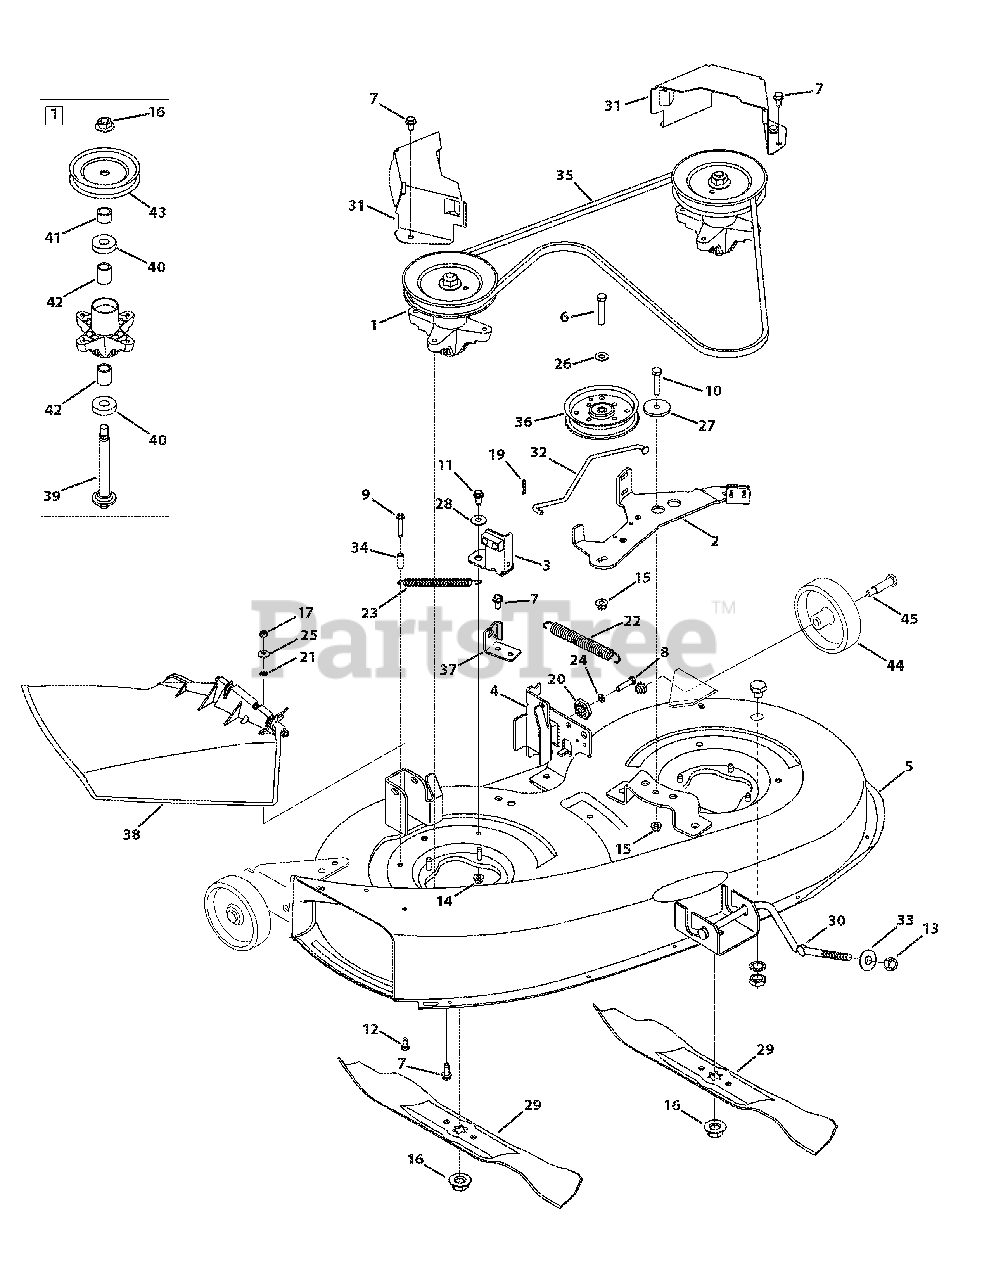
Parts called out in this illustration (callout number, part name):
1	Pulley Spindle Ass’y 5.75 dia.
2	Deck Brake Assembly
3	Deck Brake Assembly
4	Deck Hanger Brkt. Ass'y
5	Deck Shell, 38" (w/ wheel brackets)
6	Hex Screw 3/8-16 x 1.75
7	S-Tapp Scr 5/16-18 x .75
8	Hex Wash Tap Scr 5/16-18 x 1.25
9	Hex Wash HD Bolt 1/4-20 x 1.50" Lg.
10	Hex Bolt 3/8-16 x 1.25
11	Hex Bolt 5/16-18 x .75" Lg. Gr. 5
12	Hex Bolt 1/4-20 x 1.00
13	Flexloc Nut 1/2-13
14	Hex Flange Locknut 5/16-18 Gr. F, Nylon
15	Hex Flange Locknut 3/8-16 Gr. F Nylon
16	Hex Flange Locknut 5/8-18
17	Hex Nut 1/4-20 Gr. 5
19	Int. Cotter Pin .072 x 1.13" Lg.
20	Deck Adjustment Gear
21	Bolt Retainer 1/4" x .50" OD
22	Extension Spring .75 dia. x 6.37 Lg.
23	Extension Spring .50 dia x 6.37
24	L-Wash 5/16 ID
25	Cupped Washer .265 ID x .75 OD x .062
26	Flat Washer
27	Shoulder Spacer .8540 x .200
28	Shoulder Spacer
29	3 in 1 Blade 19.38" Lg.
30	Deck Rod, Front Adjustable
31	Belt Cover 5.66 dia.
32	Brake Control Rod
33	Deck Lift Pivot Cup
34	Spacer .260 x .375 x 1.030 Lg.
35	V-Belt
36	Idler Pulley w/Flange 4.25 Dia
37	Deck Engage Cable Bracket
38	Side Discharge Chute Assembly
39	Spindle Shaft 5.5
40	Ball Bearing .787 ID x 1.85 OD x .551
41	Spacer, .820 x 1.150 x .480
42	Spacer .80 x 1.10 x 1.322
43	Deck Pulley
44	Deck Wheel
45	Shoulder Bolt .498 Dia x 1.53 x 3/8-16
